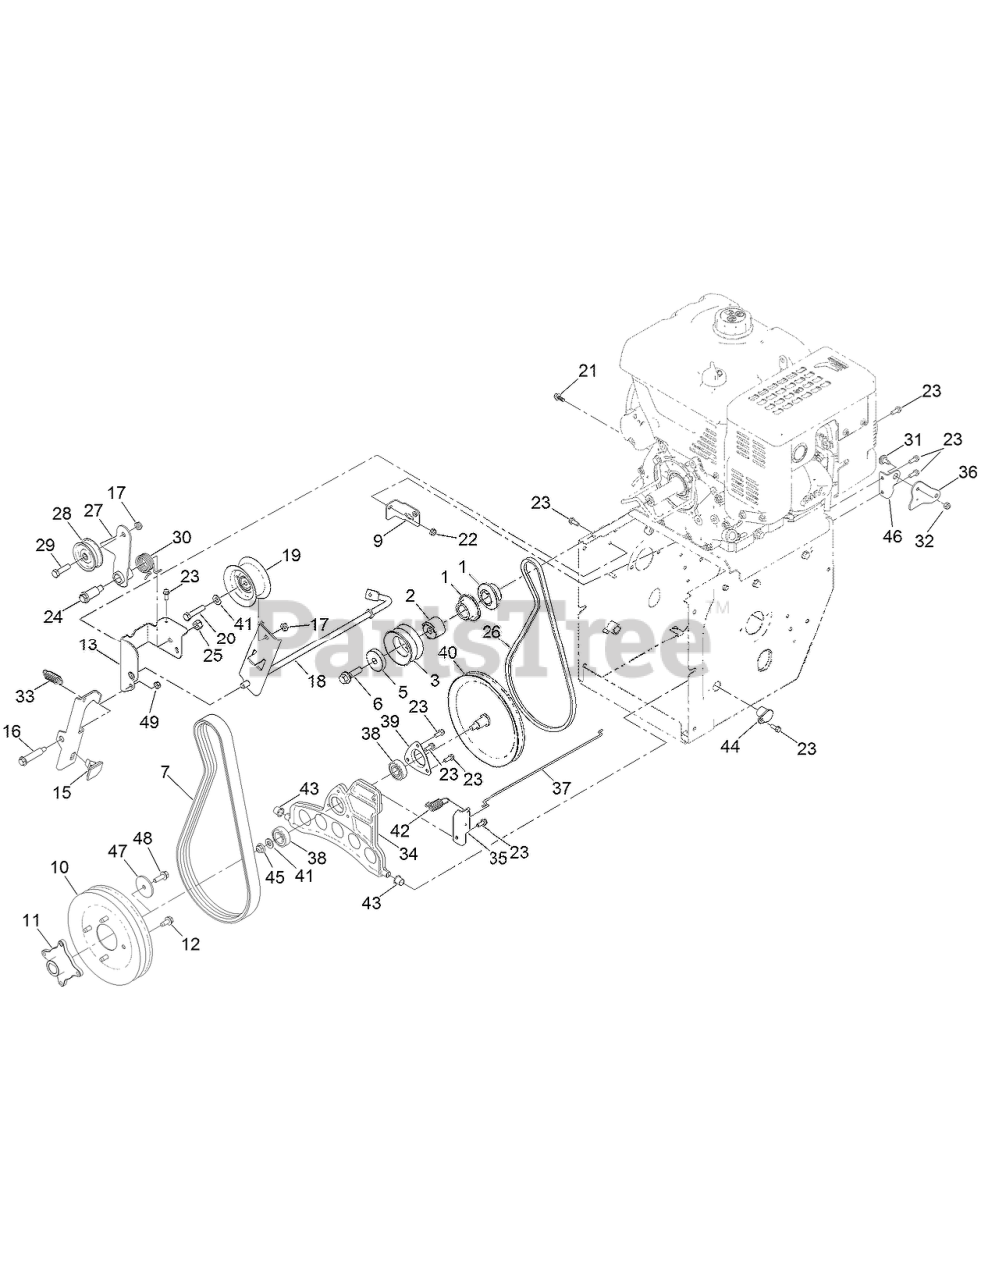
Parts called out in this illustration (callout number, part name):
1	PULLEY-TRACTION, ENGINE
2	PULLEY-SPACER
3	PULLEY-IMPELLER, DOUBLE SHEAVE
5	SUPPORT-PULLEY
6	BOLT-BLADE
7	BELT-V
9	BRACKET-CLUTCH, IMPELLER
10	PULLEY-IMPELLER, DOUBLE SHEAVE
11	HUB-PULLEY
12	SCREW-HWHTF
13	BRACKET-BRAKE, CLUTCH
15	PAD-BRAKE
16	BOLT-SHOULDER
17	NUT-HEX
18	ARM-CLUTCH, IMPELLER
19	PULLEY, IDLER
20	SCREW-HH
21	SCREW-HHF
22	NUT-HF
23	SCREW-HWH
24	BOLT-SHOULDER
25	NUT-HEX
26	V-BELT
27	ARM-IDLER, TRACTION
28	PULLEY-IDLER
29	SCREW-HH
30	SPRING-TORSION
31	SCREW-SHOULDER
32	NUT-HEX
33	SPRING-EXTENSION
34	PLATE-FRICTION, WHEEL
35	BRACKET-PLATE, TRACTION
36	BELLCRANK-DRIVE
37	LINK-DRIVE
38	BEARING-BALL
39	RETAINER-BEARING
40	PULLEY-TRACTION
41	WASHER-FLAT
42	SPRING-EXTENSION
43	BUSHING-NYLINER
44	BUSHING-PLATE, TRACTION
45	NUT-HF, NI
47	WASHER-PLAIN
48	SCREW-HHF
49	NUT-HEX
